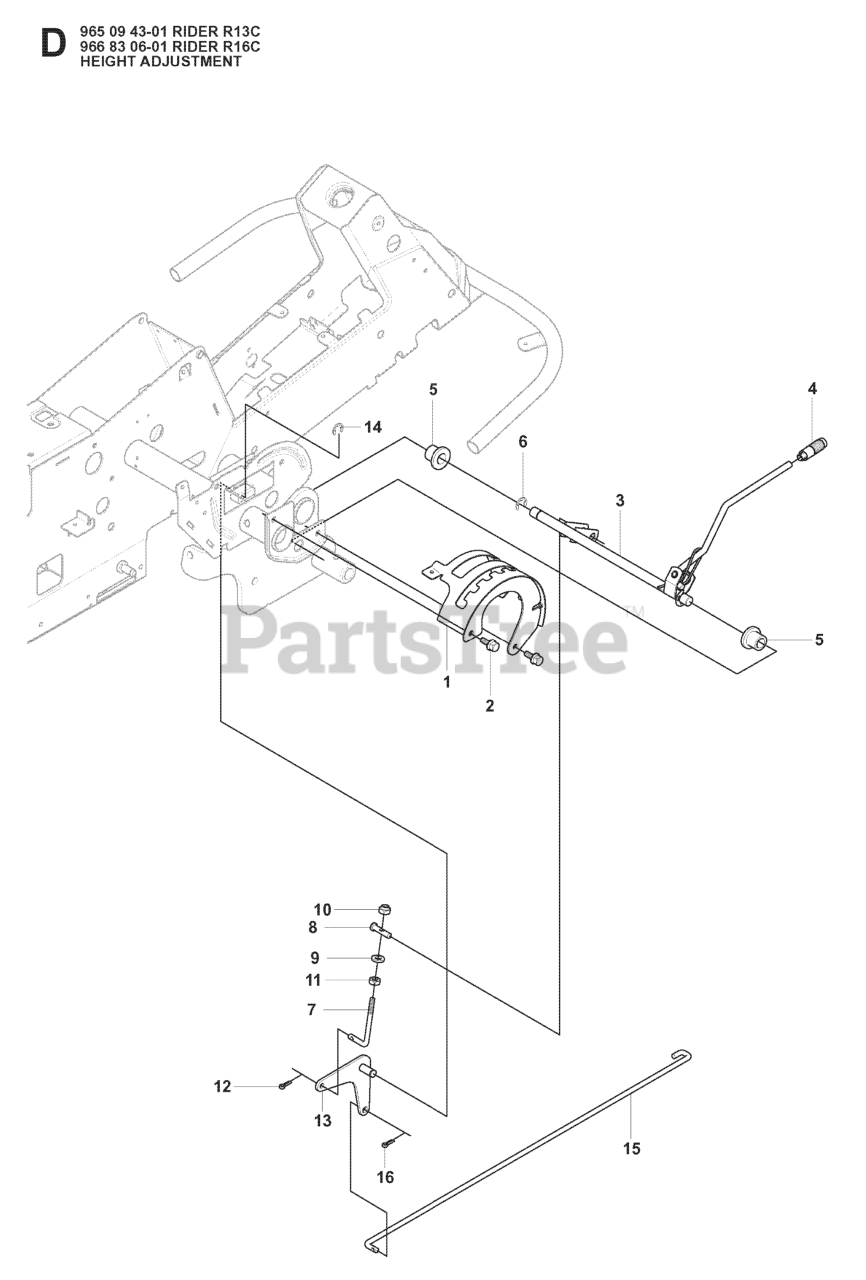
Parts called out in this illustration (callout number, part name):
1	CONTROL PLATE
3	HEIGHT ADJUSTER
4	GEAR STICK KNOB
5	BUSHING
9	WASHER
10	LOCKNUT M8
11	NUT
13	LINK HEIGHT ADJUSTMENT
14	RETAINING RING
15	CONNECTION ROD
